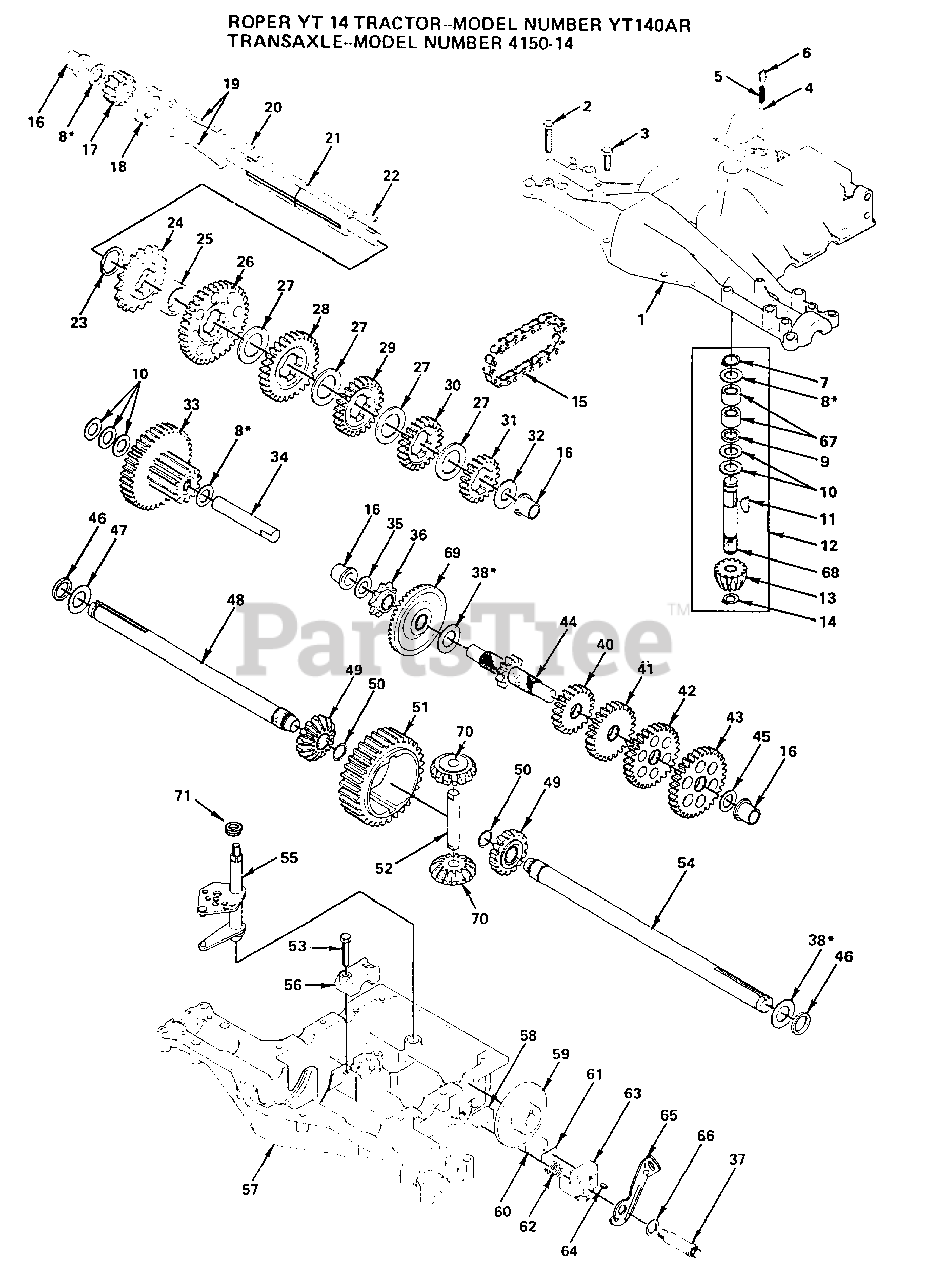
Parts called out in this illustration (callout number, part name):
1	No Desciption for Part
2	SCREW 1/4-20 X 1.31
3	SCREW 1/4-20 X .875
4	BALL DETENT
5	SPRING, DETENT
6	SCREW, SET
7	RING RETAINING
8	WASHER PLAIN
8	WASHER, PLAIN .632 X 1.00 X .026
8	WASHER, PLAIN .632 X 1.00 X .060
10	WASHER PLAIN
11	KEY WOODRUFF #9
12	ASSY KIT INPUT SHAFT
13	PINION BEVEL 14 TEETH
14	RING, RETAINING
15	CHAIN, 24 PITCHES
16	BEARING, FLANGE
17	GEAR, SPUR 14T
18	COLLAR CLUTCH
19	KEY, CLUTCH
20	KEY WOODRUFF #3
21	SHAFT, INTERMEDIATE
22	KEY, WOODRUFF, #61
23	RING, RETAINING
24	SPROCKET, 18T
26	No Desciption for Part
27	No Desciption for Part
28	No Desciption for Part
29	GEAR, SPUR, 30T
30	GEAR, SPUR, 25T
32	WASHER, PLAIN .640 X 1.37 X .061
33	ASSY, GEAR
34	SHAFT, IDLER
35	WASHER PLAIN
36	SPROCKET, 9 TEETH
37	BOLT, SHOULDER
38	WASHER PLAIN
38	WASHER, PLAIN .758 X 1.25 X .031
40	GEAR SPUR, 15 TEETH
41	GEAR, SPUR 20T
42	GEAR, SPUR, 25 TEETH
43	GEAR, SPUR, 31 TEETH
44	SHAFT, DRIVE
45	WASHER, PLAIN .632 X 1.00 X .060
47	WASHER, PLAIN .758 X 1.25 X .031
48	GEAR, MITER 15T
49	GEAR, MITER 15T
50	RING, RETAINING
51	GEAR, SPUR, 32T
52	SHAFT, CROSS
53	SCREW TAPPING
55	ASSY, SHIFTER & SEAL
56	CAP, SUPPORT
57	HOUSING, LOWER
58	PUCK, FRICTION
59	DISC, BRAKE
60	PUCK, FRICTION
62	SPRING, COMPRESSION
63	SPRING, COMPRESSION
65	ASSY, LEVER, ACTUATING
66	WASHER, PLAIN
67	BEARING, NEEDLE
69	GEAR, BEVEL, 42 TEETH
70	GEAR, MITER, 15 TEETH
